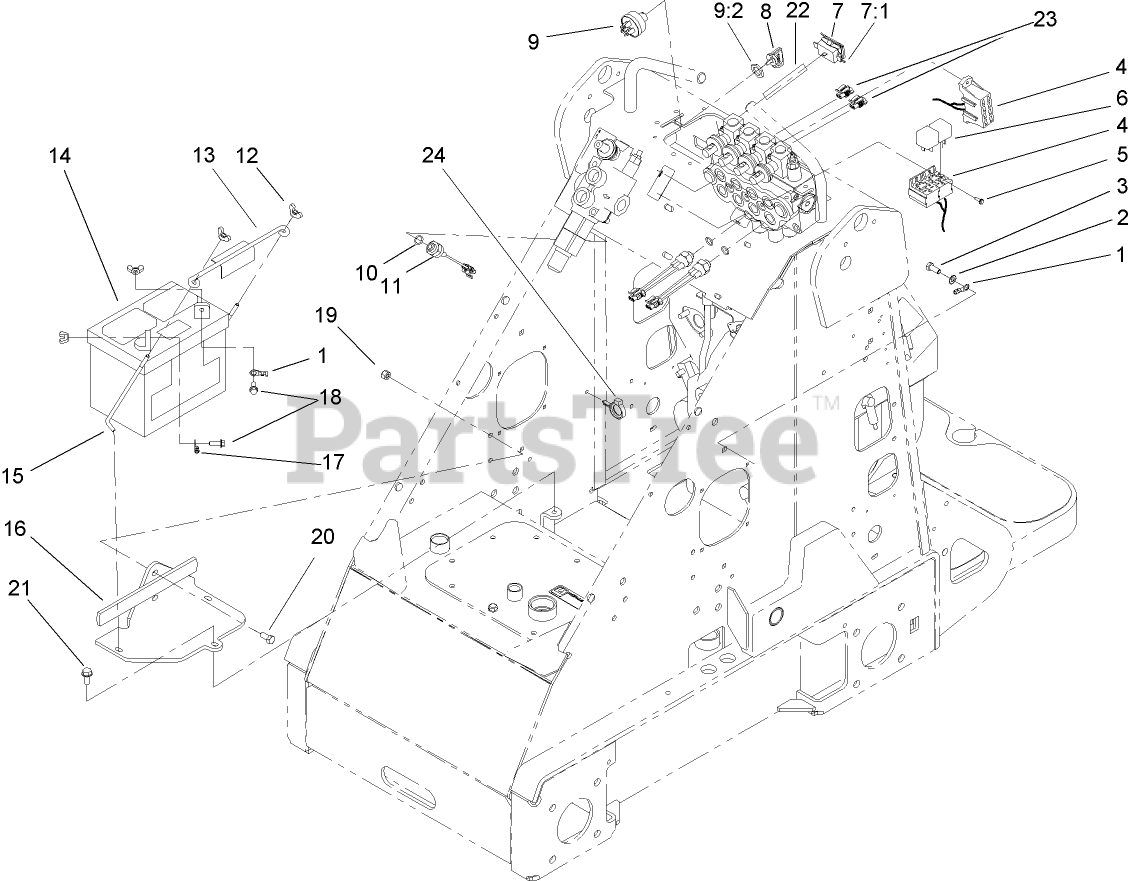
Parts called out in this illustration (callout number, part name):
1	WIRE ASM
2	WASHER-LOCK
3	SCREW-HH
4	HARNESS-WIRE
5	SCREW-HWHTF
6	RELAY
7	HOURMETER-INDUCTIVE
7:1	CLIP-MOUNTING
8	KEY-IGNITION
9	IGNITION SWITCH ASM
10	O-RING
11	SWITCH-BALL
12	NUT-WING
13	HOLDDOWN-BATTERY
14	BATTERY-DRY
15	RETAINER-BATTERY
16	BATTERY MOUNT ASM
17	CABLE-POSITIVE
18	SCREW-HHF
19	NUT-LOCK, NI
20	SCREW-HH
21	SCREW-HWHTF
22	WIRE-HOURMETER
23	Connector-Female
24	CLAMP-HOSE
